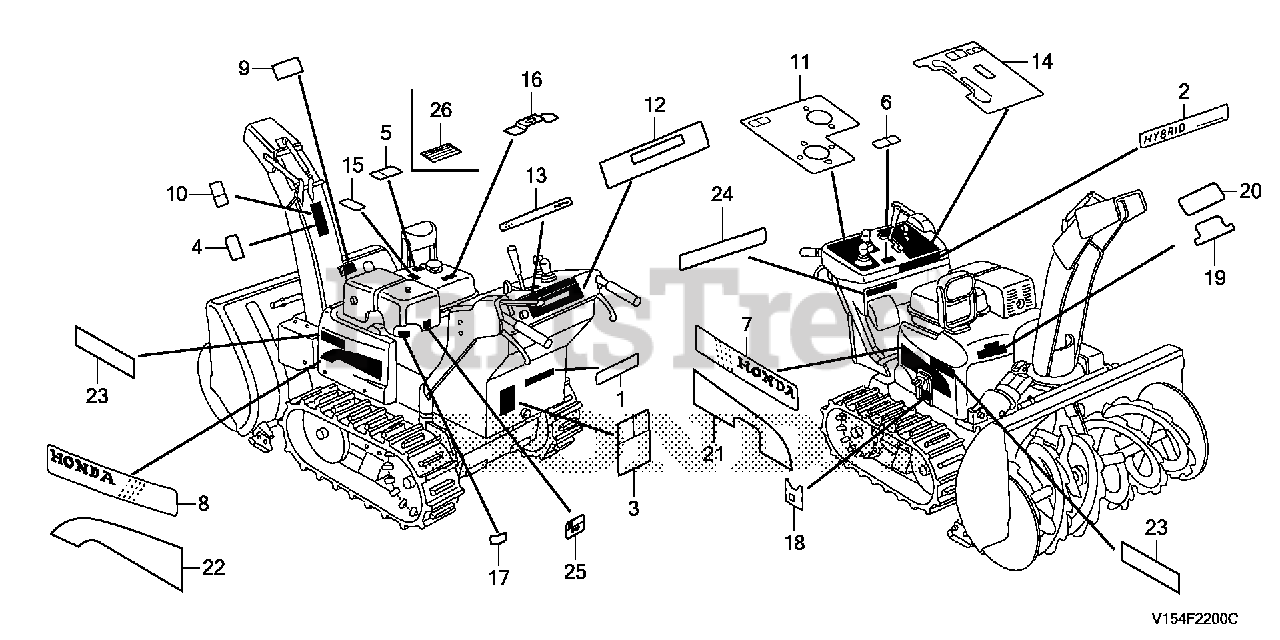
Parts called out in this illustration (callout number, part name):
1	LABEL, BATTERY PRODUCT DANGER
3	LABEL, WARNING (ENGLISH)
4	LABEL, WARNING (ENGLISH)
9	MARK, HOUSING DANGER (ENGLISH)
10	MARK, DISCHARGE DANGER (ENGLISH)
11	MARK, CONTROL OPERATION (ENGLISH)
12	MARK, ENGINE SWITCH (ENGLISH)
14	MARK, THROTTLE (ENGLISH)
18	MARK, OIL CAUTION
20	MARK, EMBLEM (HS1336I)
21	MARK, R. STRIPE
22	MARK, L. STRIPE
23	MARK A, HONDA
24	MARK B, HONDA
25	MARK, FUEL INDICATION (ENGLISH)
